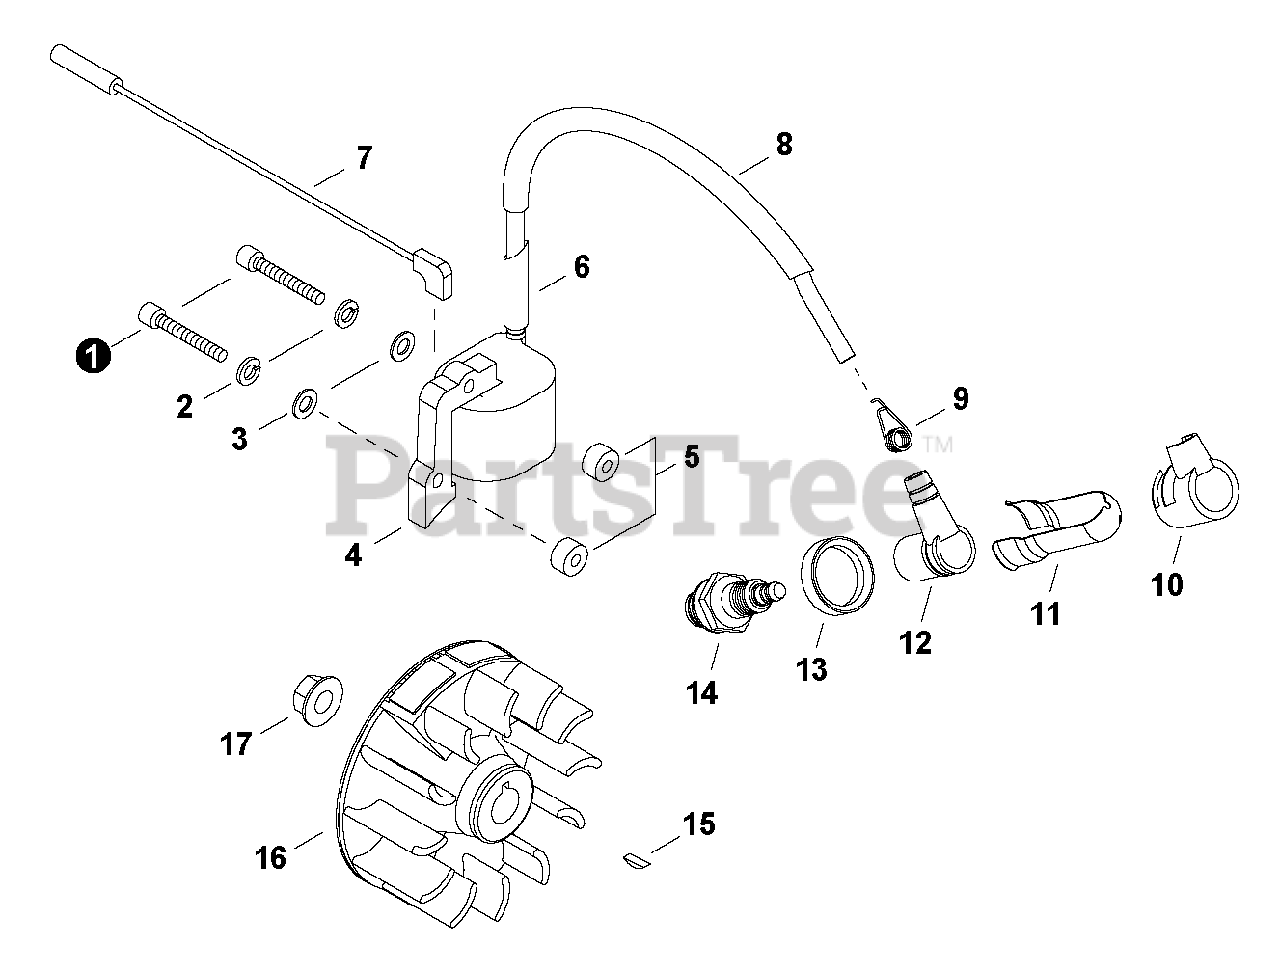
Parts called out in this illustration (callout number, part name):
1	BOLT 4×30
2	WASHER, SPRING 4 MM
3	WASHER 4 MM
4	COIL, IGNITION
5	INSULATOR 4.2×11×6
6	TUBE, INSULATOR
7	LEAD - GROUND
9	TERMINAL, SPARK PLUG
10	COVER, CAP
12	CAP, SPARK PLUG
13	SEAL, SPARK PLUG
14	SPARK PLUG - BMR6A
15	KEY, WOODRUFF 3×10
16	FLYWHEEL
